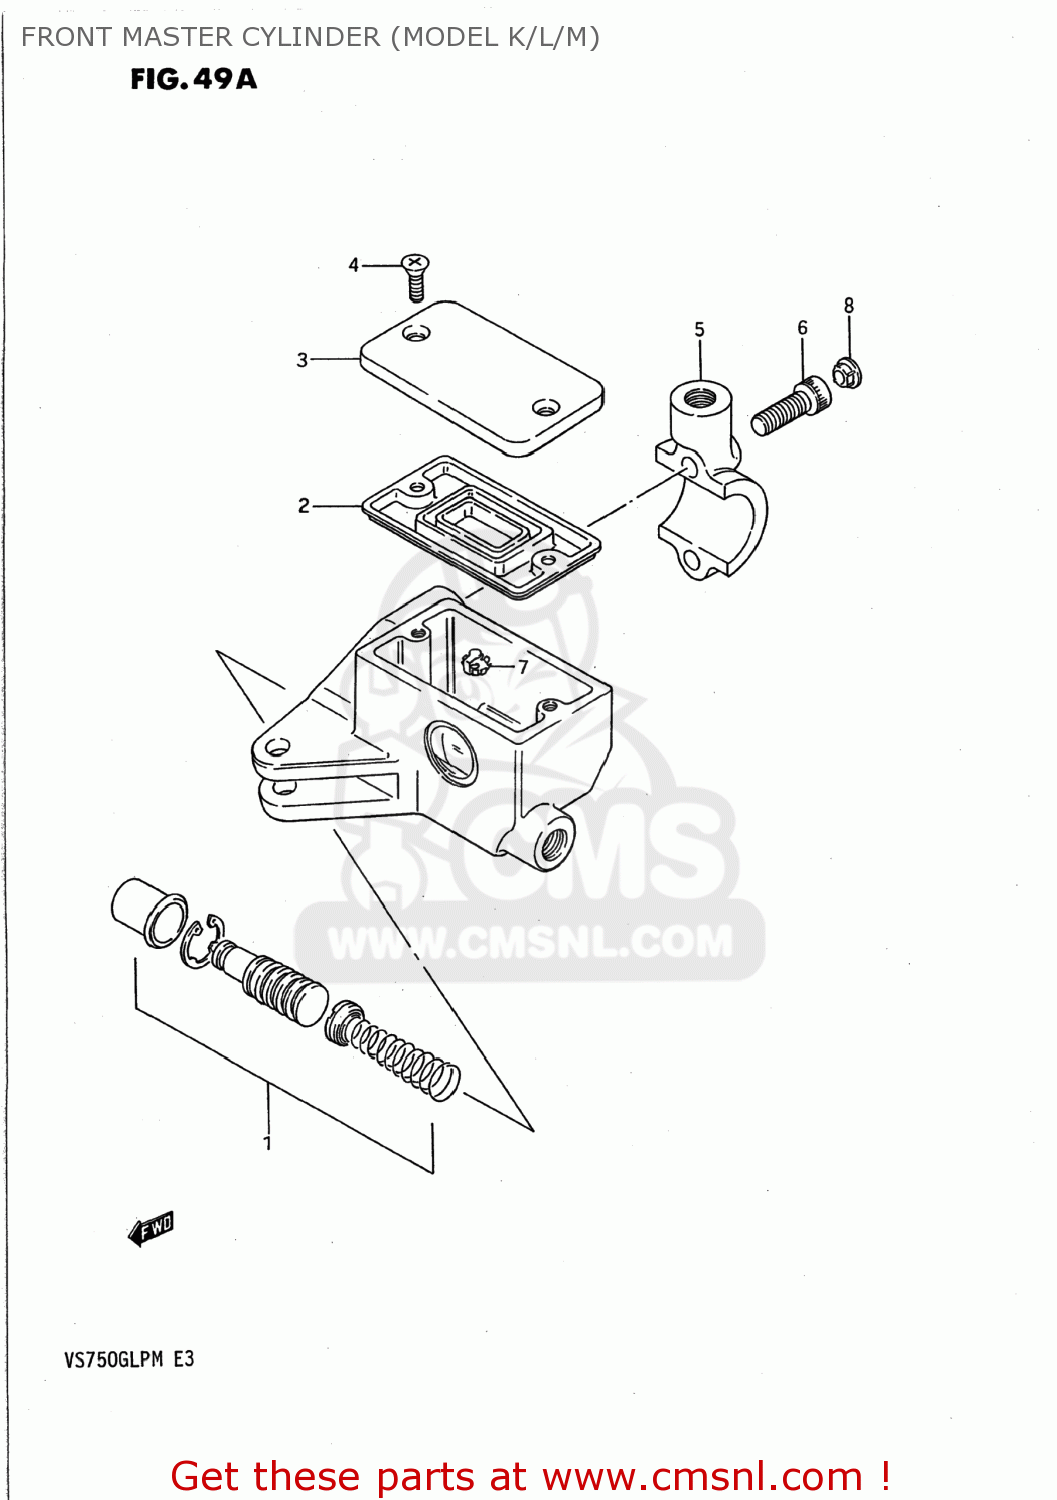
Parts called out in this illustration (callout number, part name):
1	CUP SET,MASTER CYLINDER
2	3
3	CAP
4	SCREW,RESERVOIR CAP
5	HOLDER
6	BOLT ,6X20
7	PROTECTOR
8	CAP(OD:10)
